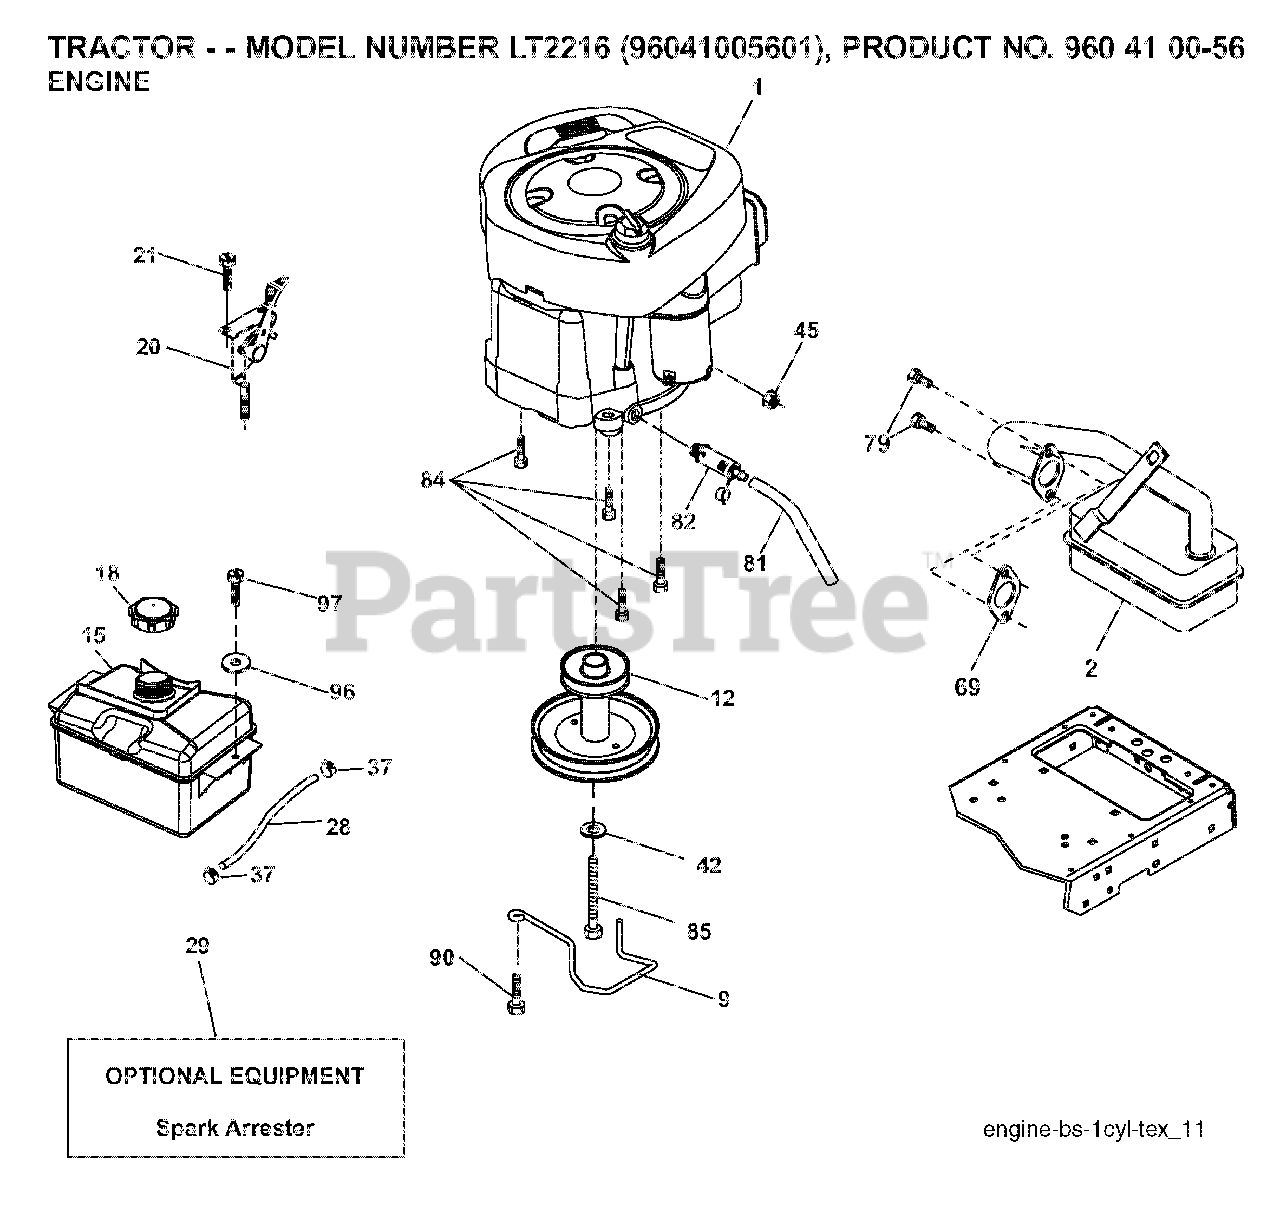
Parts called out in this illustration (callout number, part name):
9	KEEPER.BELT.ENGINE.3.25
12	PULLEY ENGINE
15	TANK FUEL FRT 1.5 GAL
18	FUEL CAP
20	CONTROL.TH/CK.C.
21	SCREW
28	LINE.FUEL.20
29	ARRESTER SPARK (OPTIONAL)
37	HOSE CLAMP
42	LOCKWASHER
45	NUT
69	REPL BY 532 27 22-93
79	SCREW.SOCKET HD.5/16-1
81	TUBE, DRAIN OIL ASM.
82	PLUG DRAIN OIL EASY
84	SCREW.3/8-16
85	BOLT HEX 7/16-20X4-1/4"
90	SCREW 3/8-16X1
97	SCREW HEXWSHR 1/4-20X3/4
